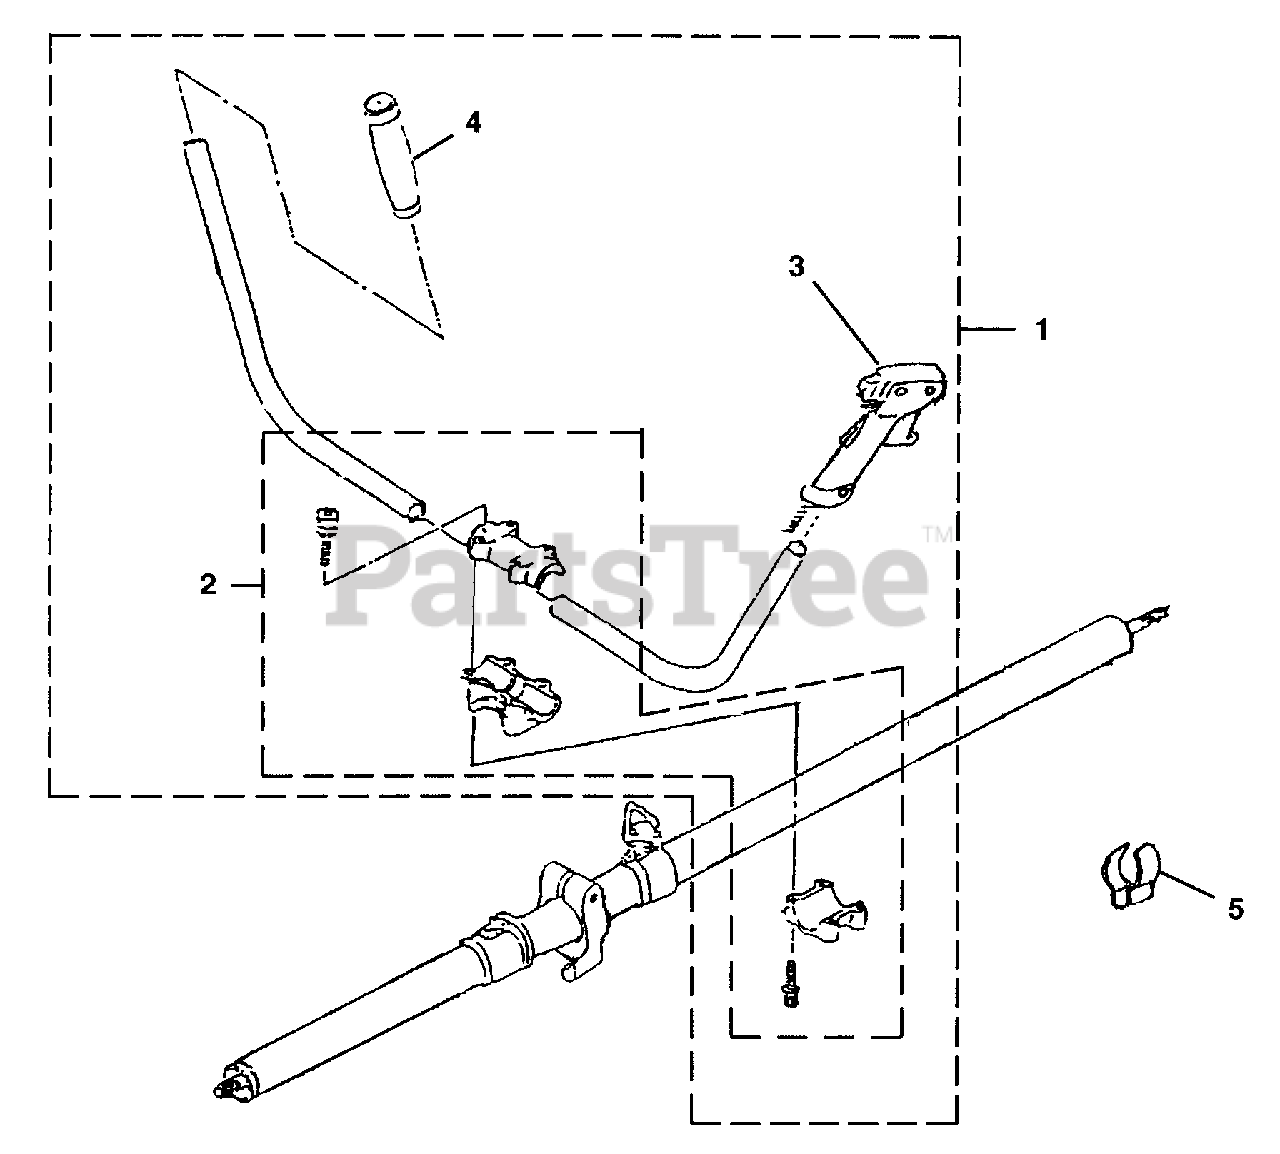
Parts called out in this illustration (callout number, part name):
1	HANDLE ASSEMBLY
2	HANDLE BRACKET
3	CONTROL LEVER
5	CLAMP, WIRE
